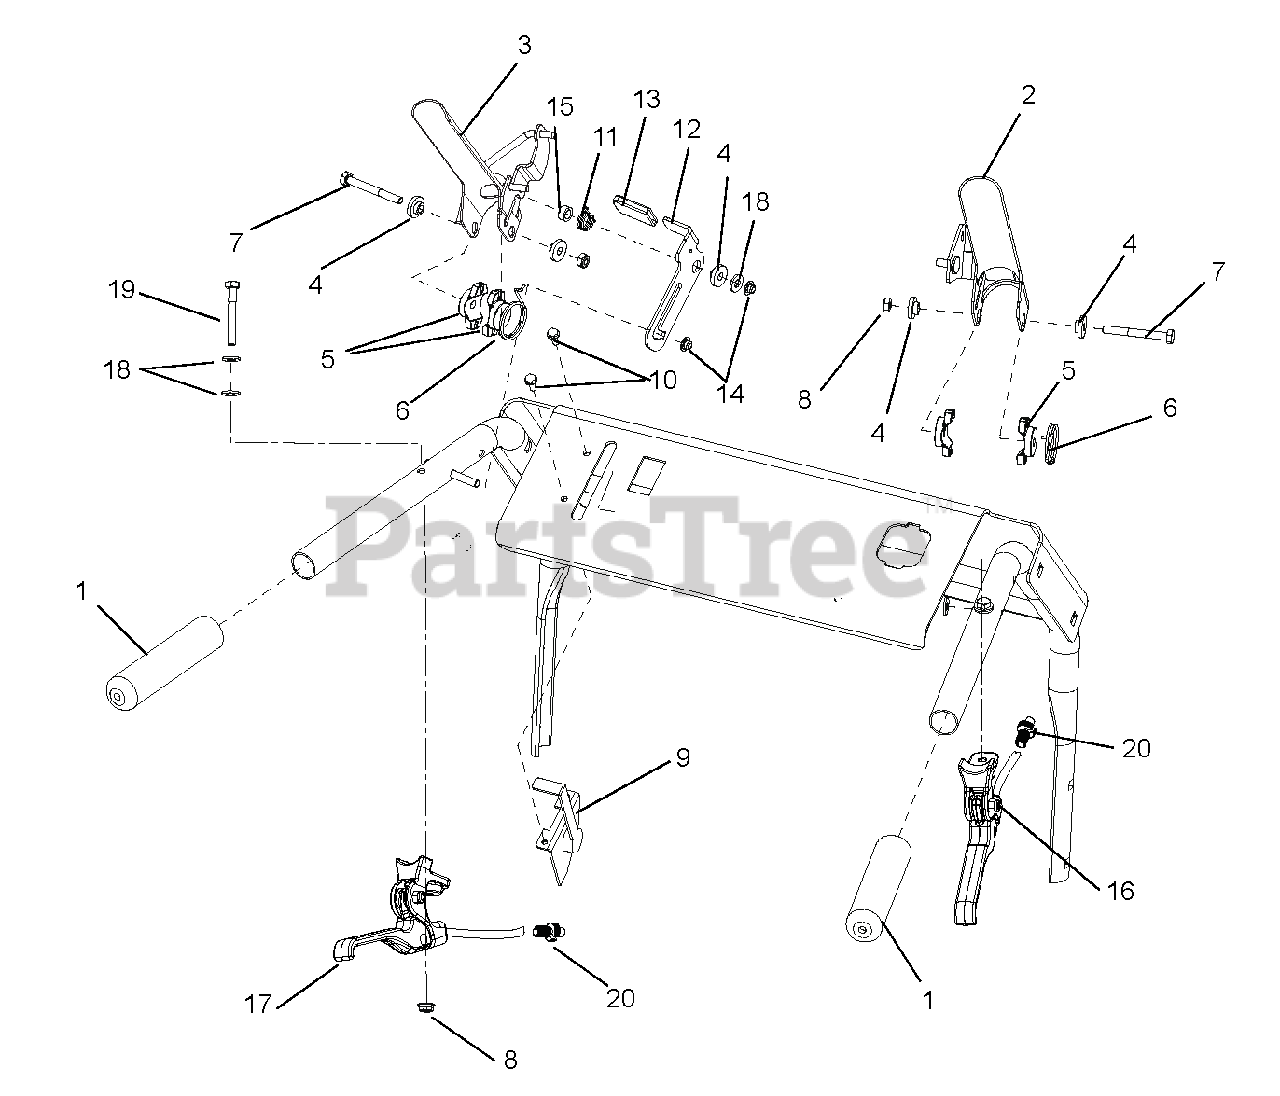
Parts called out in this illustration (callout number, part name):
1	HANDLE GRIP
2	PADDLE, WAW PARK BRAKE
3	WMT-PADDLE, WAW PTO - CE
4	BSHG, FLG .266X.42X.150 PM
5	SPACER, HANDLEBAR
6	SPRING, TORSION
7	@BLT-HEX .25-20X2.25 GR5 YWZC
8	NUT-JAM-NYL .250-20 W/INSERTYZ
9	CABLE, WAW THROTTLE
10	@SCR-TAP 10-24X.50 HWH TR YWZC
11	SG-TORS
12	BRKT-LEVER, INTERLOCK
13	GRIP, THUMB LATCH
14	PUSH NUT, .25
15	TUBE-SPACER .33X.50X.XX
16	CONTROL-LEVER W/CABLE FORWARD
17	CONTROL-LEVER W/CABLE REVERSE
18	@WSHR-FL-STL.281X.62X.065 YWZC
19	@BLT-HEX .25-20X2.00 GR5 YWZC
20	CABLE ADJUSTER, STEEL
